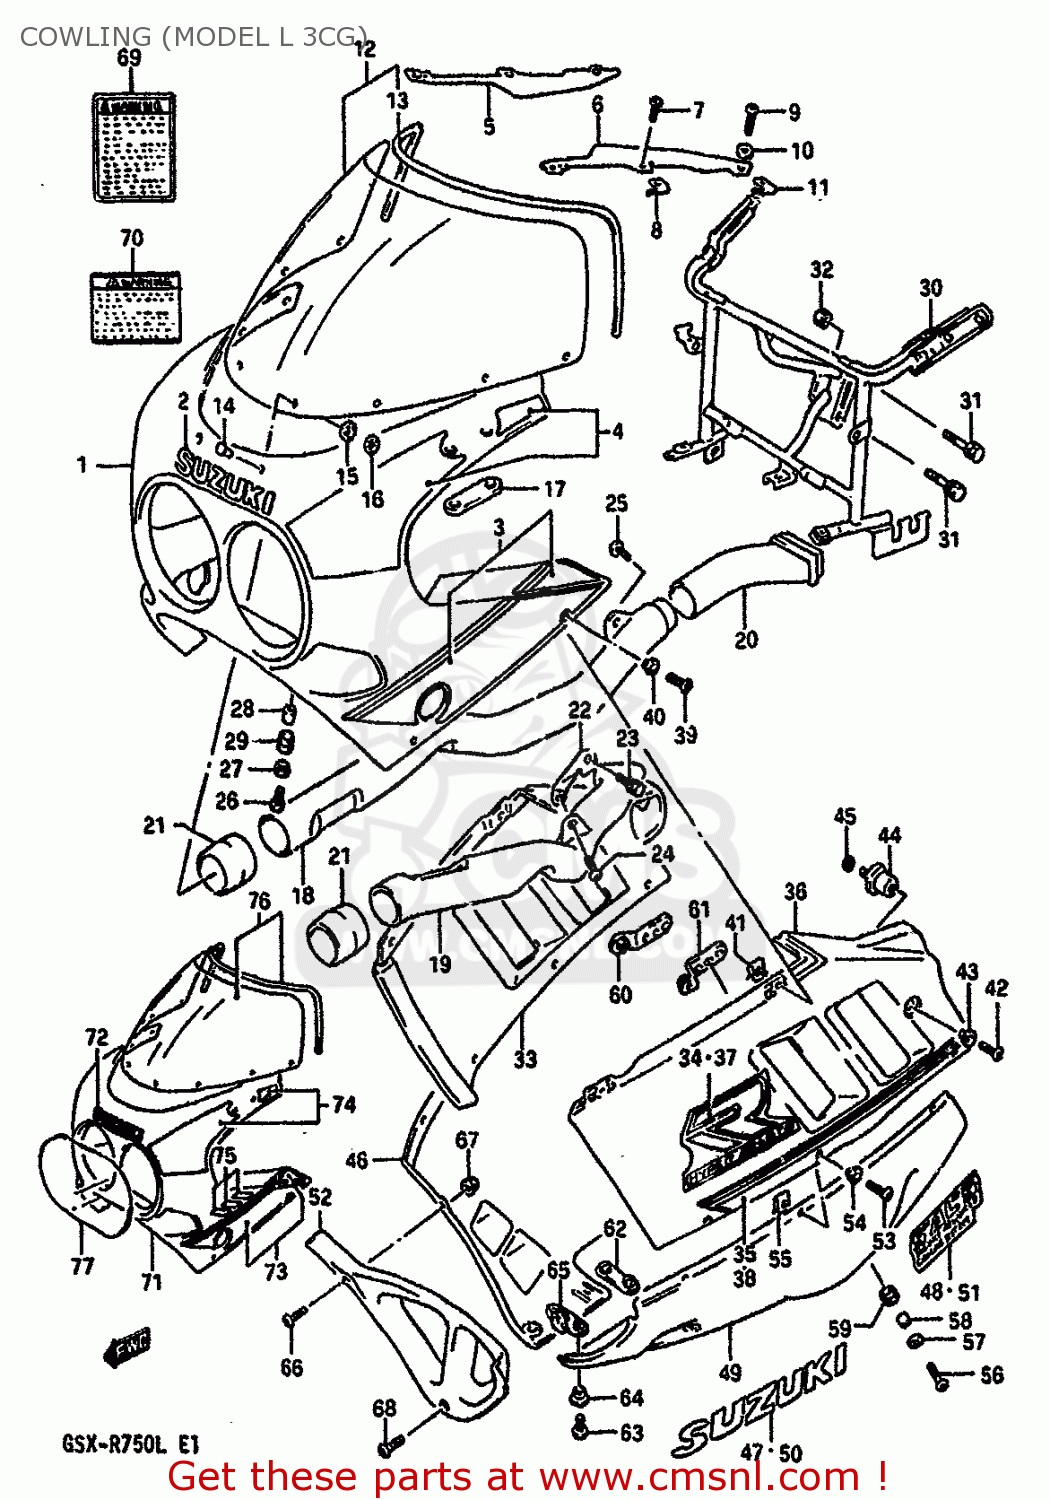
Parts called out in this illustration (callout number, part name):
1	BODY ASSEMBLY,COWLING
2	EMBLEM,COWLING FR
3	TAPE SET,COWLING,UPPER
4	TAPE SET,FRONT
5	PANEL,COWLING UPR,R
6	PANEL,COWLING UPR,L
7	SCREW(5X10)
8	NUT
9	SCREW(5X14)
10	WASHER(5.2X11X1)
11	NUT
12	WINDSCREEN
13	MOLDING
14	PIN,WINDSCREEN
15	CUSHION
16	NUT
17	CUSHION,RR VIEW MIRRORR
18	PIPE,AIR INTAKE,FRONT
19	PIPE,AIR INTAKE,FRONT
20	PIPE,AIR INTAKE RR,R
21	JOINT,AIR INTAKE
22	PLATE,AIR INTAKE,LEFT
23	BOLT
24	SCREW 6X12
25	SCREW
26	SCREW(6X20)
27	WASHER(6.5X18X1)
28	SPACER
29	CUSHION
30	BRACE,COWLING
31	BOLT
32	NUT ,8MM
33	COVER,COWLING SIDE,RIGHT
34	EMBLEM,COWLING SIDE,RIGHT
35	TAPE,COWLING SIDE STRIPE
36	COVER,COWLING SIDE,LEFT
37	EMBLEM,COWLING SIDE,L
38	TAPE,COWLING SIDE STRIPE
39	SCREW(5X18)
40	WASHER(5.2X14X1.5)
41	NUT,HEADLAMP HOUSING,UPPER
42	SCREW(6X12)
43	WASHER(6.3X16X1.5)
44	CUSHION,COWLING
45	WASHER,LOCK
46	COWLING,UNDER RH (BLACK/SILVER)
47	EMBLEM
48	EMBLEM,SACS
49	COWLING,UNDER
50	EMBLEM,COWLING UNDER,L
51	EMBLEM,SACS
52	COWLING,UNDER,CENTER
53	SCREW(5X18)
54	WASHER(5.2X14X1.5)
55	NUT,HEADLAMP HOUSING,UPPER
56	SCREW(6X20)
57	WASHER(6.5X18X1)
58	SPACER
59	CUSHION
60	BRACKET
61	BRACE,COWLING UNDER,LH
62	BRACE,COWLING LWR COVER RR
63	SCREW(6X16)
64	WASHER(6.3X16X1.5)
65	BRACE,COWLING LWR COVER
66	SCREW(5X14)
67	NUT
68	SCREW(6X16)
69	LABEL (WARNING SCREEN)
70	LABEL, WARNING SAFETY
71	BODY ASSY,COWLING (BLACK)
72	EMBLEM,COWLING FR
73	TAPE SET,COWLING,UPPER
74	TAPE SET,COWLING,UPPER
75	TAPE SET,COWL
76	SCREEN SET,WIND
77	SCREEN,HEAD LAMP
